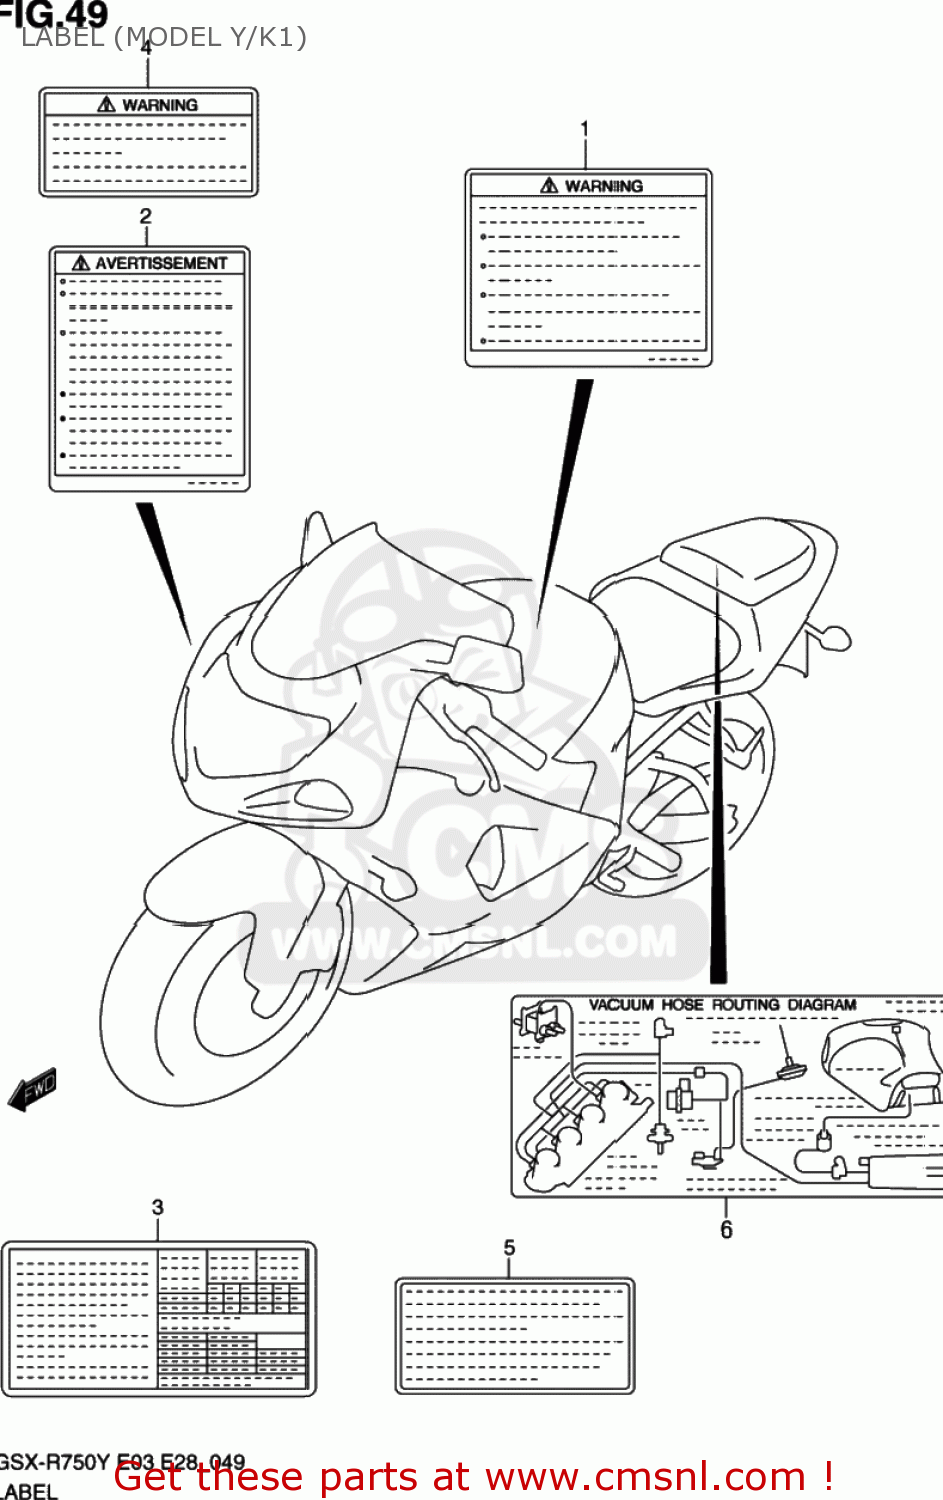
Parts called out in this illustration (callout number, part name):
1	LABEL,GENERAL WARNING
2	LABEL,WARNING SCREEN
3	LABEL,TIRE INFORMATION
4	LABEL,WARNING STEERING
5	LABEL (MANUAL NOTICE)
6	LABEL,VACUUM HOSE ROUTING
7	MANUAL,OWNER'S GSX-R750Y
